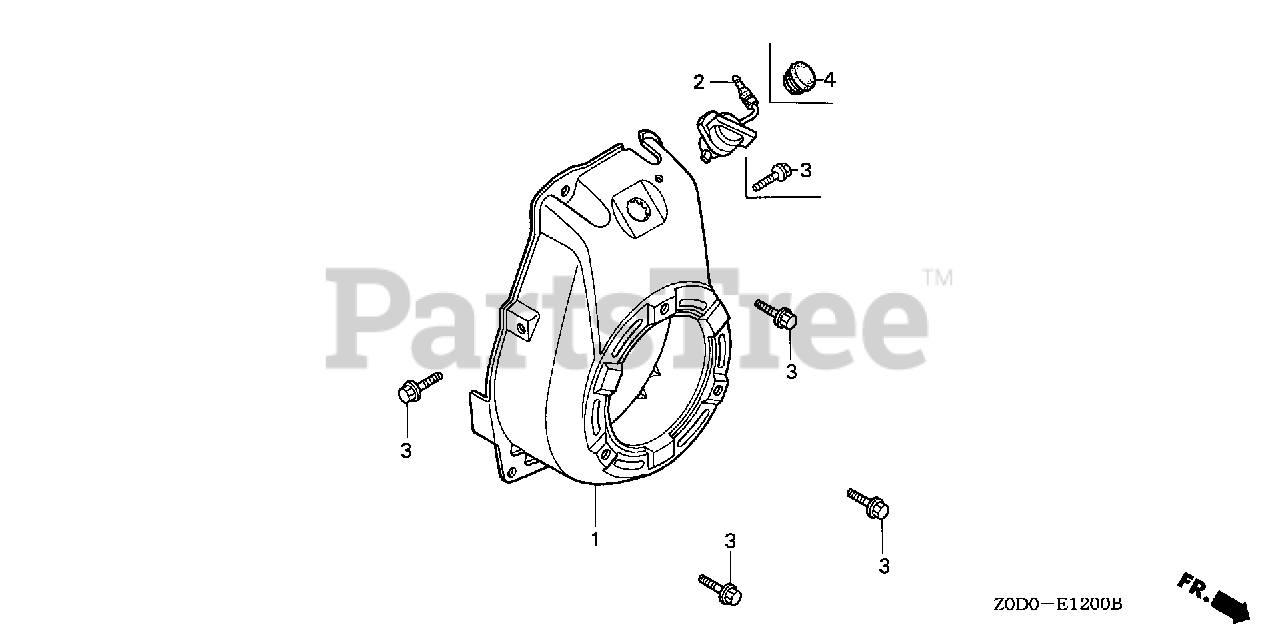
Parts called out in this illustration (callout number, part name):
1	COVER, FAN *NH1* (BLACK)
1	COVER, FAN *R280* (POWER RED)
2	SWITCH ASSY., ENGINE STOP
3	BOLT, FLANGE (6X14) (CT200)
